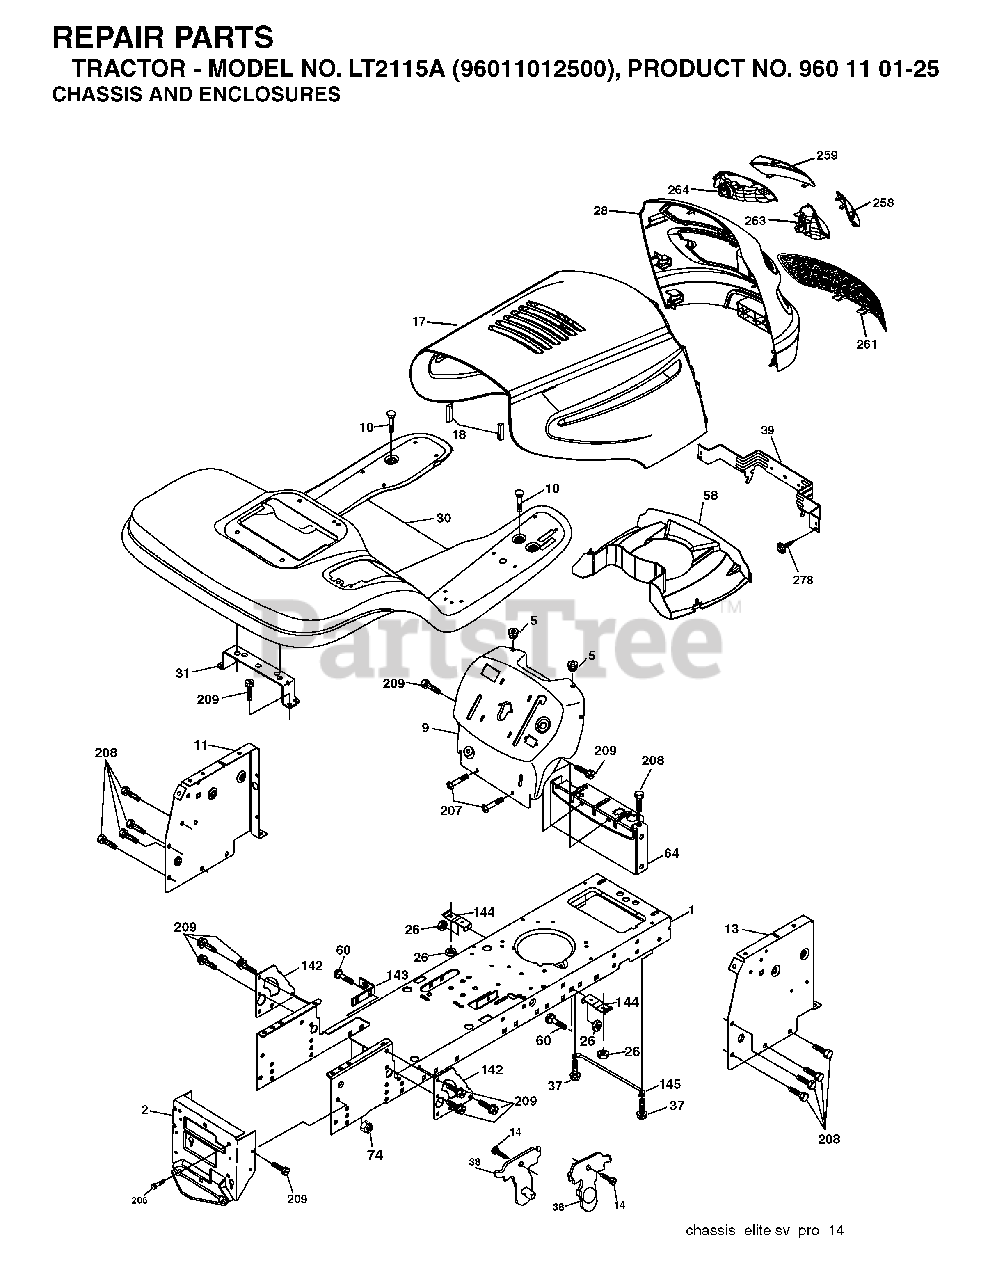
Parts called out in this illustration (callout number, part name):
1	CHASSIS STAMPING
2	DRAWBAR, 12GA
5	BUMPER.RUBBER.HOOD
10	BOLT D
11	PANEL.DASH.LH.LTX
14	SCREW LT
18	BUMPER.HOOD.LARGE.1.75"
26	NUT
37	SCREW LT
38	BRACKET.ASM.PIVOT.MOWER.REAR
39	BRACKET PIVOT LASER
64	DASH LOWER
74	LOCKNUT
142	PLATE REINFORCEMENT
143	BRACKET, SWAYBAR CHASSIS
144	BRKT, FOOT REST
145	ROD PIVOT CHASSIS/HOOD
206	SHOULDER BOLT 5/16-18TT
207	SCREW, 5/16-18 X 1/2
208	SCREW 3/8-16X1/2
209	SCREW, 3/8-16X3/4
263	BEZEL GRILL RH
264	BEZEL GRILL LH
278	SCREW
